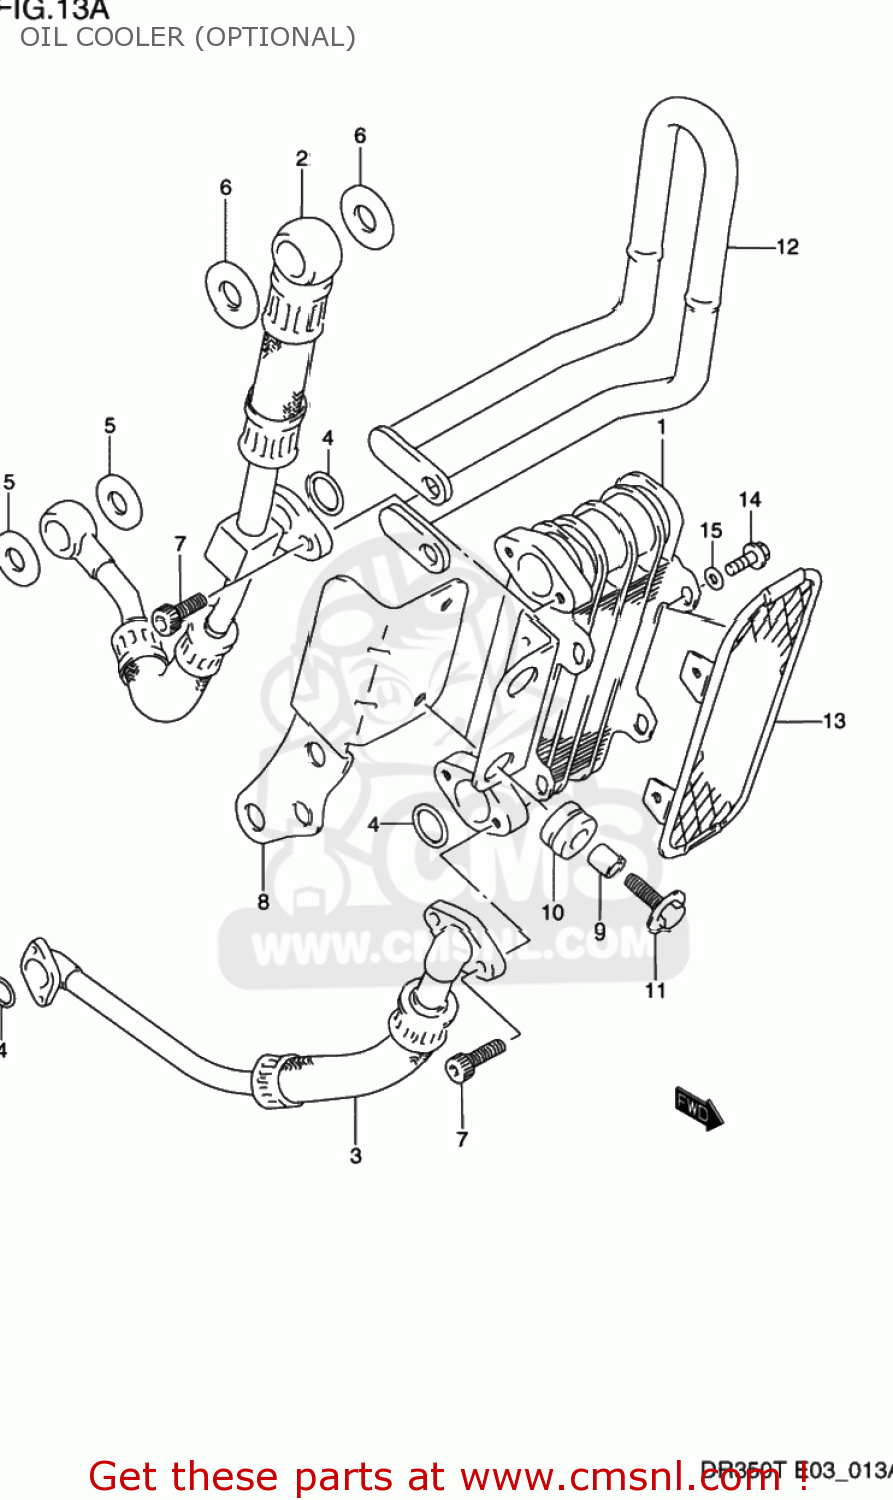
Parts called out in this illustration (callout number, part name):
1	COOLER ASSY,OIL
2	HOSE,OIL COOLER UPR
3	HOSE,OIL COOLER LWR
4	O RING(D:2.4,ID:12.3)
5	GASKET(12X17X1) (NAS)
6	GASKET(16X22X2) (NAS)
7	BOLT
8	BRACKET,OIL COOLER
9	SPACER (6.8X10X10)
10	CUSHION
11	BOLT 6X20
12	GUARD,OIL COOLER
13	BUMPER,OIL COOLER
14	BOLT
15	WASHER,LOCK
